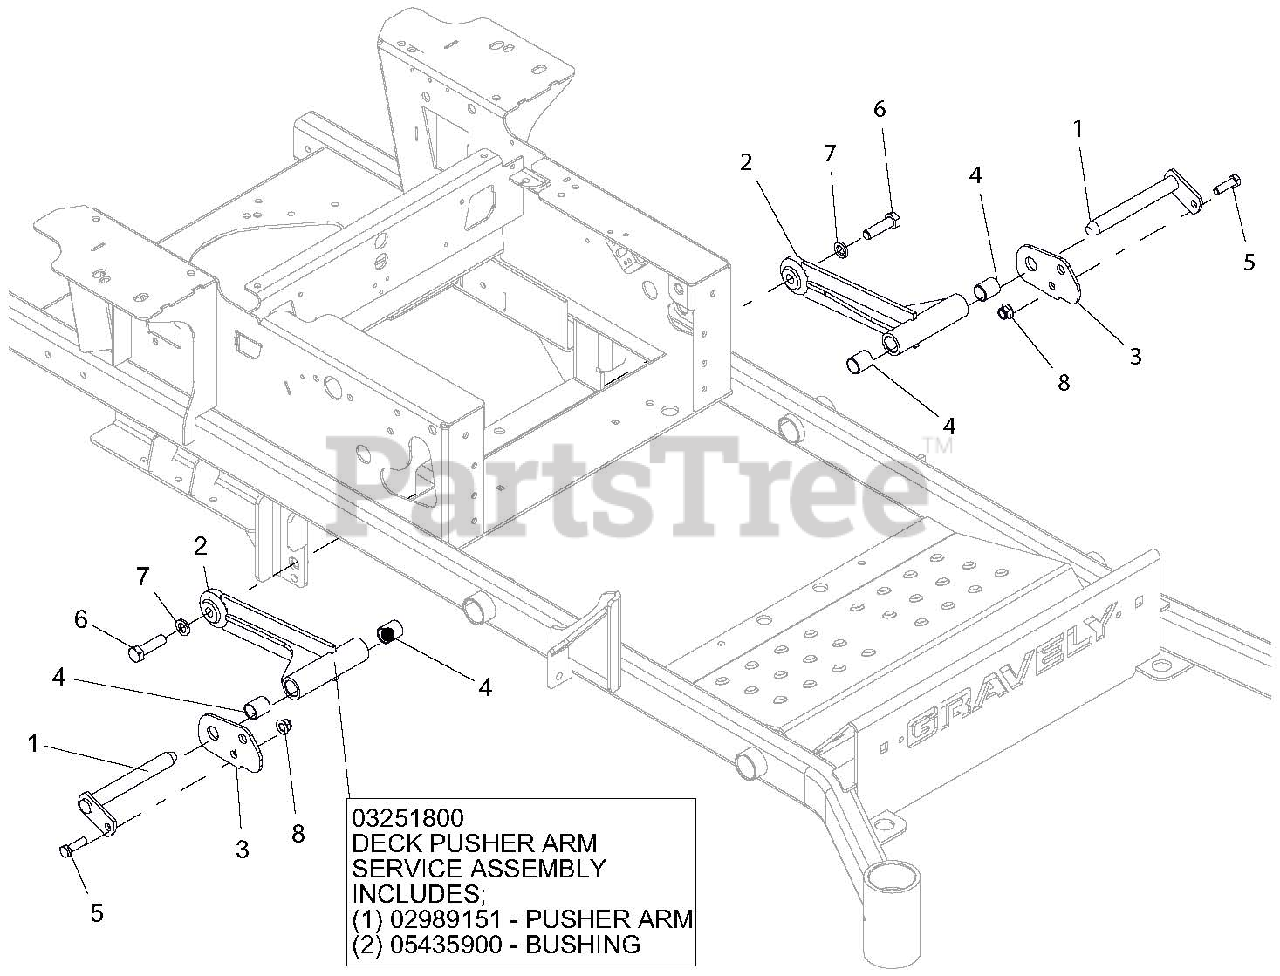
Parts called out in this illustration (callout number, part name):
1	WLDMT, MOWER MTG. PIN
2	DECK PUSHER ARM WLDMT - BLK
2	DECK PUSHER ARM SERVICE ASSEMBLY
2	PUSHER ARM
2	BUSHING
3	PLATE, PT REAR CHAIN MTG DOUBLER-RED
4	BRG, .750 X .875 X 1.000
5	BLT-HEX .38-16X1.25 GR5 YWZC
6	BLT-HEX .50-13X1.75 GR5 YWZC EP80
7	WSHR-LK .50X.125 REG YWZC
8	NUT-LK-NYL-FLG .38-16 YWZC
